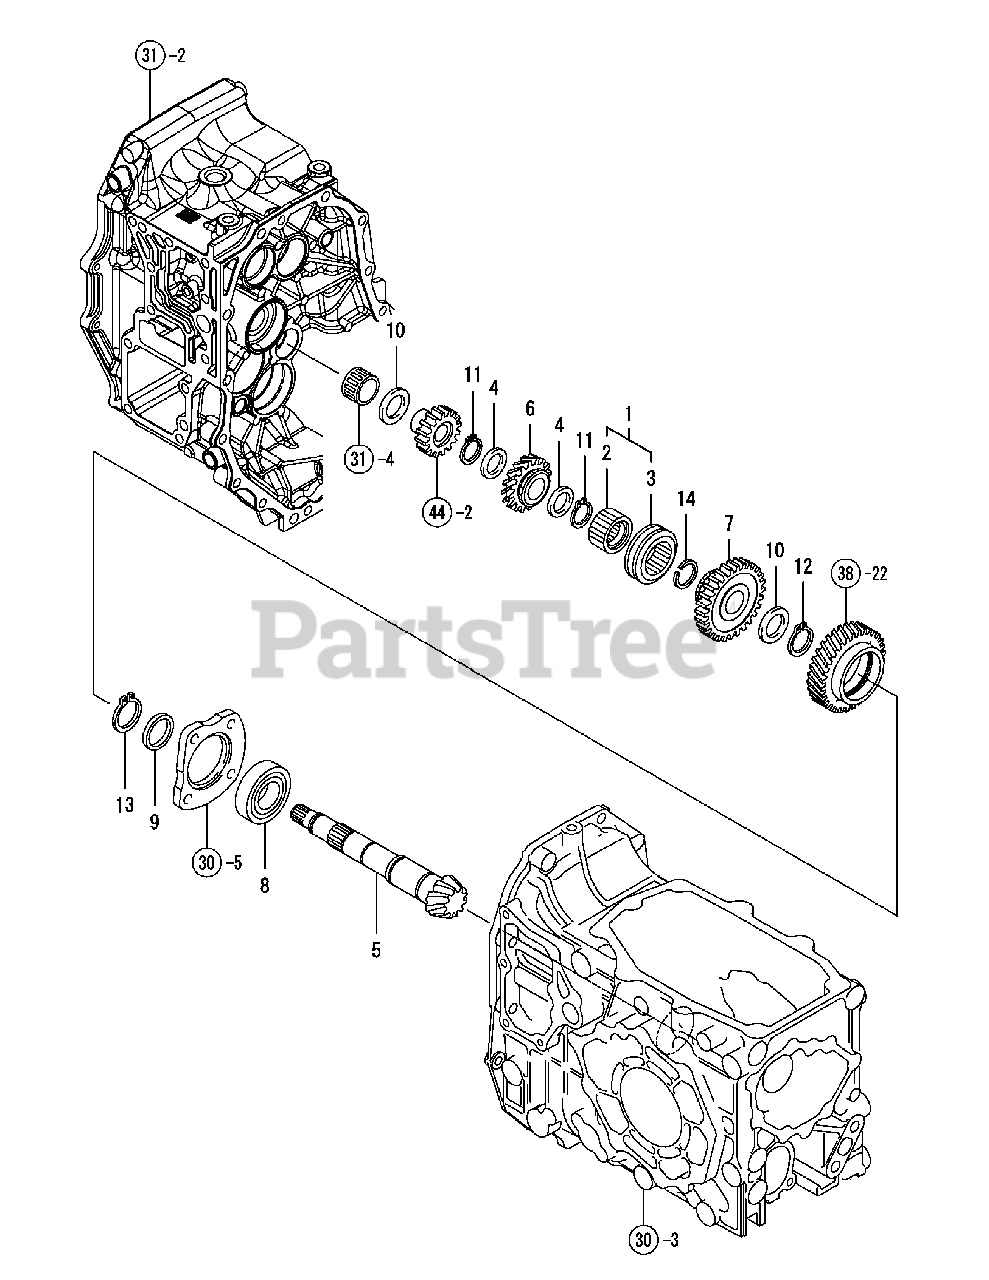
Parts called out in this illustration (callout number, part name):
1	Collar Set,Spl H/L
2	Spline Collar, H/L
4	Washer 22X32X2.5
5	Shaft, Counter
6	Gear(Counter High
7	Gear, Counter Low
8	Bearing 6206Rsh2
9	Collar 30*38*4.5
10	Thrust Washer (C)
